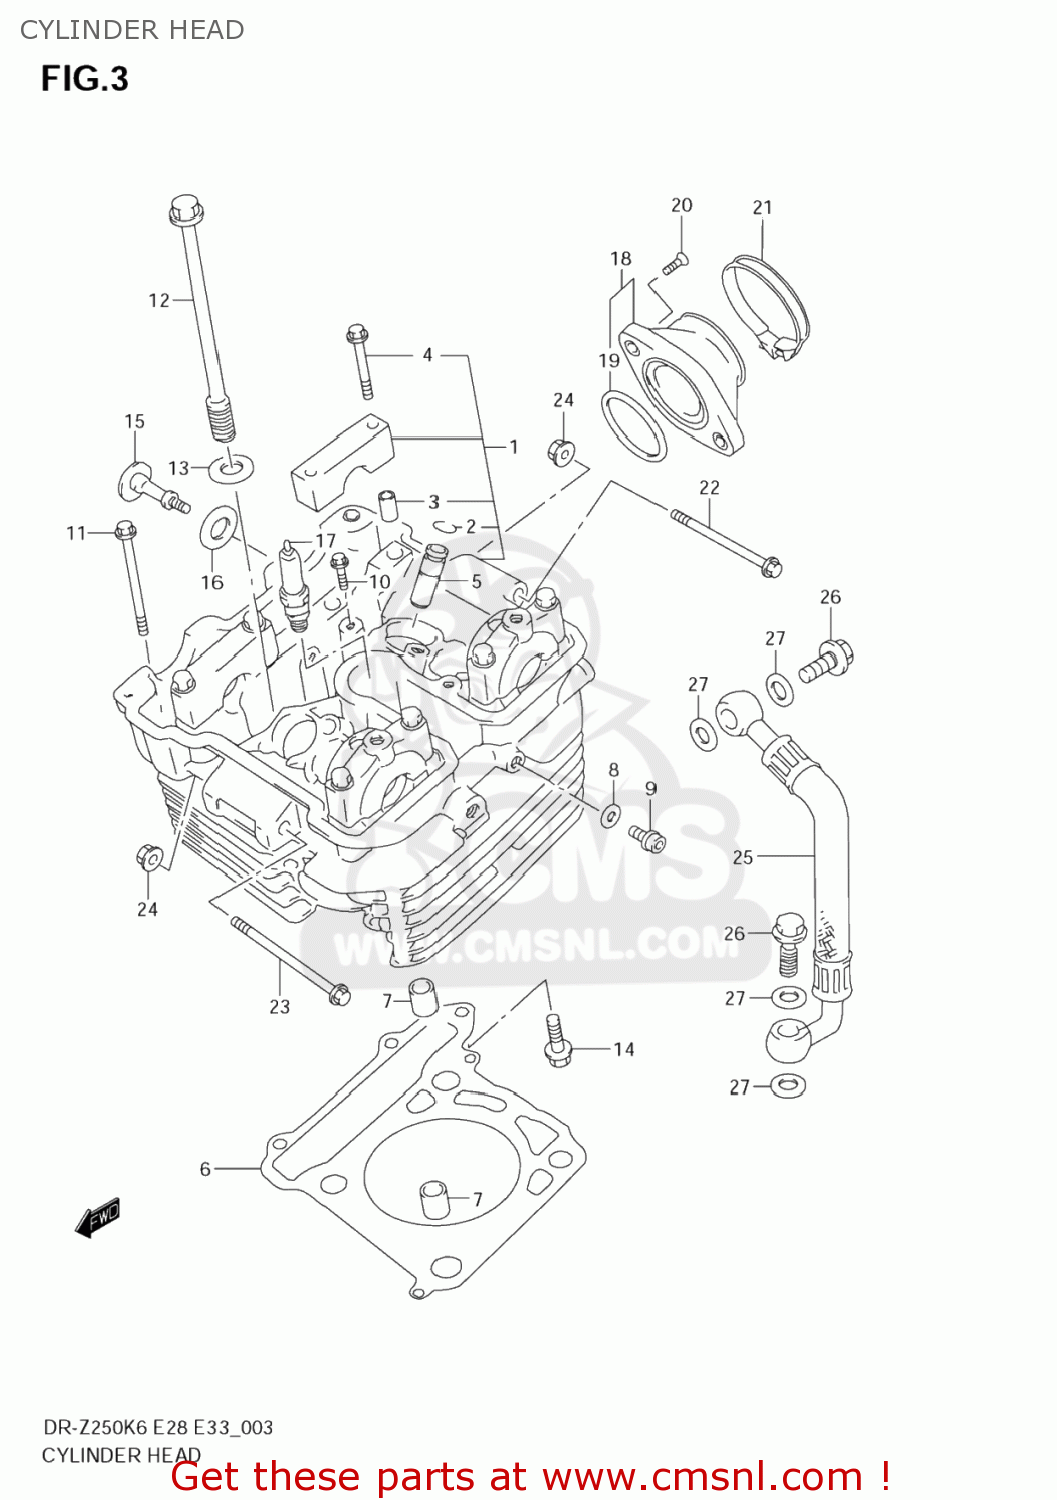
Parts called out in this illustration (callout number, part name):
1	HEAD ASSY,CYLINDER
2	RING,SNAP
3	PIN(6.2X8X11)
4	BOLT(6X45)
5	GUIDE,VALVE(OS:0.3)
6	GASKET,CYLINDER HEAD
7	PIN
8	GASKET(5.8X13X1.2) (NAS)
9	BOLT
10	BOLT
11	BOLT(6X70)
12	BOLT(10X160)
13	GASKET(10.2X20X2).3 (NAS)
14	BOLT
15	BOLT,CYL HEAD SIDE FACE
16	WASHER,HEAD COVER
17	PLUG,SPARK(CR8E)
18	PIPE ASSY,INTAKE
19	O RING(D:1.9,ID:40.7)
20	SCREW(6X16)
21	CLAMP
22	BOLT(8X60)
23	BOLT(8X70)
24	NUT
25	HOSE,T/M OIL OUTER
26	BOLT UNION
27	GASKET(10.1X16X1) (NAS)
